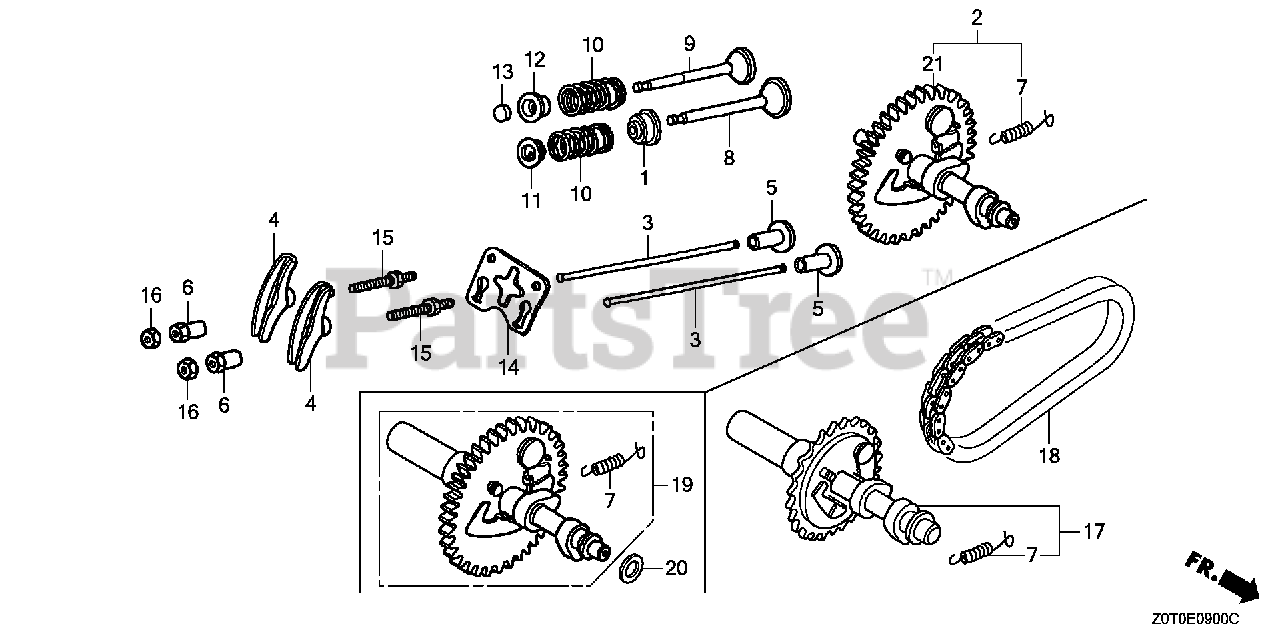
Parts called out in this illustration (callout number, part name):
1	SEAL, VALVE STEM
3	ROD, PUSH
4	ARM, VALVE ROCKER
5	LIFTER, VALVE
6	PIVOT, ROCKER ARM
8	VALVE, IN.
9	VALVE, EX.
10	SPRING, VALVE
11	RETAINER, VALVE SPRING (EXHAUST SIDE)
12	RETAINER, VALVE SPRING (EXHAUST SIDE)
14	PLATE, PUSH ROD GUIDE
15	BOLT, PIVOT (8MM)
16	NUT, PIVOT ADJ.
21	CAMSHAFT ASSY.
